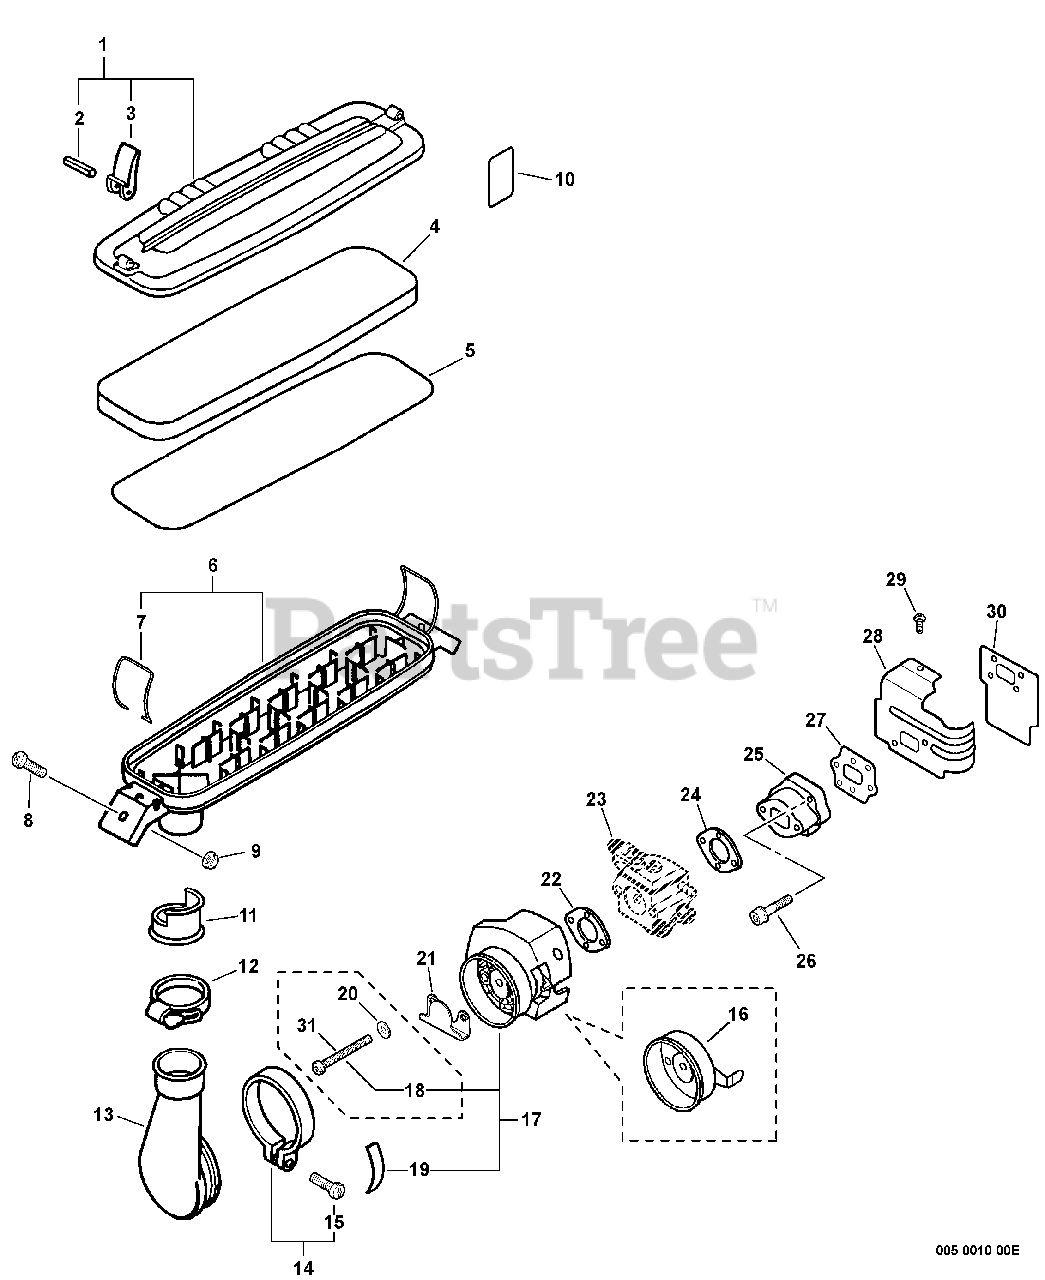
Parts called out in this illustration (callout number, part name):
1	AIR FILTER COVER ASSY
2	PIN - SPRING -- 3X25
4	FILTER, AIR
5	FILTER, AIR - FOAM
6	AIR FILTER CASE ASSY
7	RING, RETAINING
8	SCREW - 5X14
9	NUT - 5 -- FLANGE
10	TIE, CABLE - LARGE
12	CLAMP, HOSE
13	ADAPTOR, INTAKE
14	CLAMP KIT
15	SCREW - 5X25
16	BRACKET, AIR CLEANER - METAL
17	BRACKET KIT - PLASTIC
18	SCREW - 5X57
19	LABEL - CHOKE
20	WASHER - 6
21	PLATE, PREVENT
22	GASKET, INTAKE
23	CARBURETOR
24	GASKET, INTAKE
25	INSULATOR, INTAKE
26	SCREW - 5X25
27	GASKET, INTAKE
28	COVER, CYLINDER - INTAKE
29	SCREW - 5X10
30	SHIELD, INTAKE
31	SCREW - 5X55
